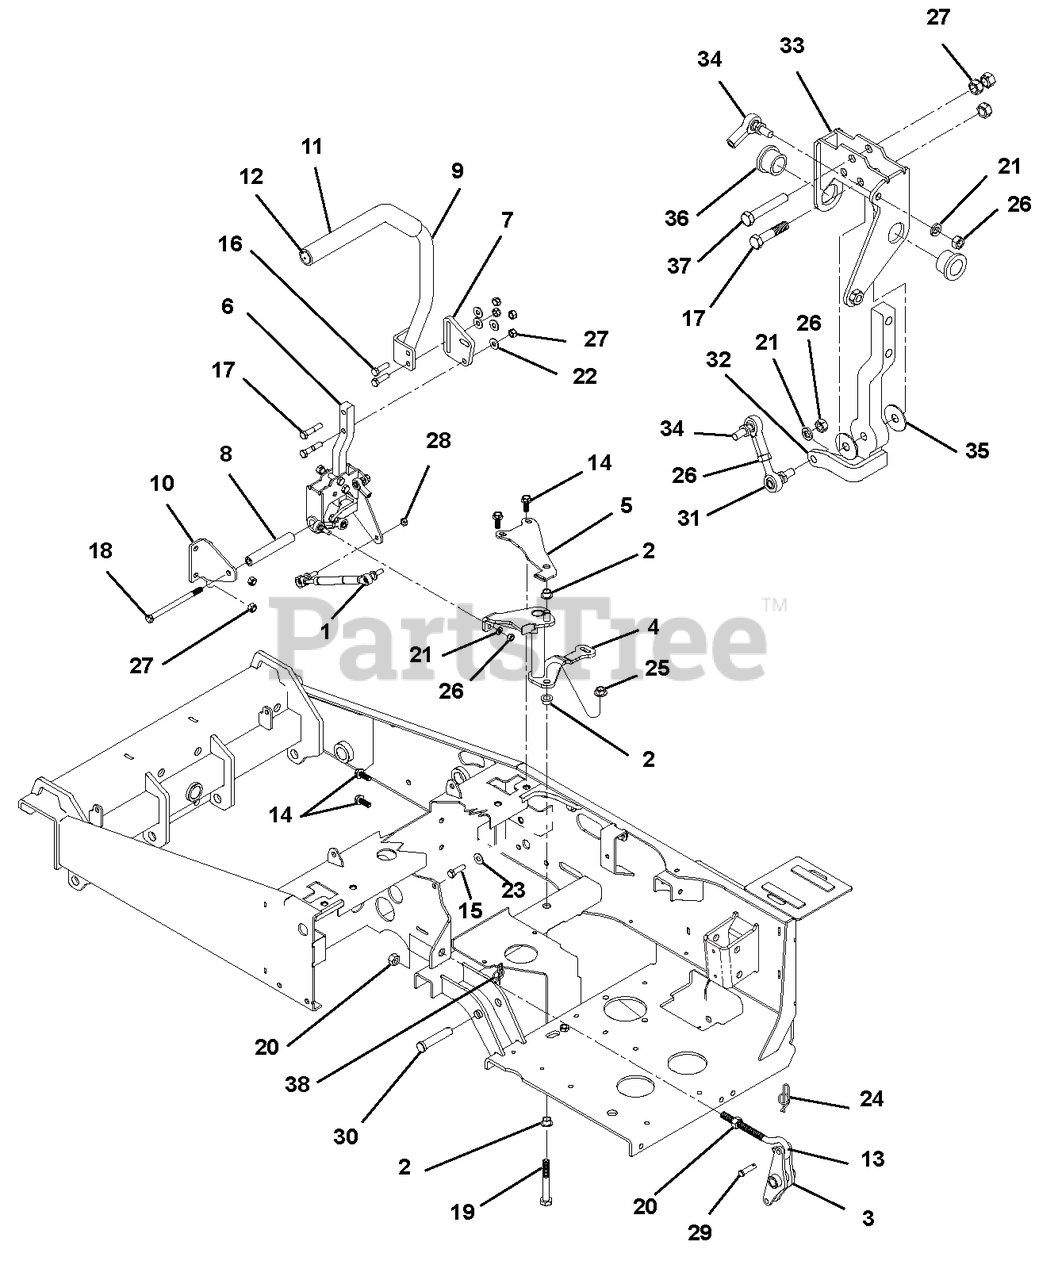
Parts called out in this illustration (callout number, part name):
1	DAMPNER, STEERING CONTROL
2	BRG, FLG .502X.629X.421
3	WLDT, SPRING PIVOT
4	WLDT, RH PARK BRAKE CONTROL
4	WLDT, LH PARK BRAKE CONTROL
5	EAR, RH BRAKE PIVOT
5	EAR, LH BRAKE PIVOT
6	WLDT, RH STEERING BAR
6	WLDT, LH STEERING BAR
7	PLATE, HANDLE HEIGHT
8	TUBE, RD .750 X .179 X 4.69 Y
9	WLDT, RH STEERING HANDLE
9	WLDT, LH STEERING HANDLE
10	PLATE, BENT
11	FOAM GRIP
11	GRIP, HANDLE
12	PLUG, 7/8" END
13	EYEBOLT, 1/2-13X1.00X4.50 FL Y
14	BOLT, 3/8-16X1.00 FGH 8 Y
15	@BLT-HEX .38-16X.75 GR5 YWZC
16	@BLT-HEX .38-16X1.25 GR5 YWZC
17	@BLT-HEX .38-16X1.75 GR5 YWZC
18	@BLT-HEX .38-16X5.50 GR5 YWZC
19	@BLT-HEX .50-13X2.75 GR5 YWZC
20	@NUT-HEX .50-13 YWZC
21	@WSHR-LK .31X.078 REG YWZC
22	@WSHR-FL-STL.38X.875X.083 YWZC
23	@WSHR-FL-STL.438X1.00X.083 YWZ
24	RING, RUE .375 X .054 X 1.254
25	NUT-LK-CONE .50-13 GR C YWZC
26	NUT-HEX .312-24 YWZC
27	NUT-LK-FLG .375-16 PL
28	NUT-LK-TOP M8-1.25 YWZC
29	PIN-CLEV .375X1.38X1.14 YWZC
30	PIN-CLEV .625X3.00X2.77 YWZC
31	BALL JOINT, RH 5/16 MALE W/STD
32	WLDT, RH STEERING BAR
32	WLDT, LH STEERING BAR
33	WLDT, HANDLE CONTROL RH
33	WLDT, HANDLE CONTROL LH
34	BALL JOINT, RH 5/16 FMAL W/STD
35	WASHER, .400X1.27X.062 NYLON
36	BUSHING, .750 X 1.00 X .750
37	@BLT-HEX .38-16X2.25 GR5 YWZC
38	RING, RUE .625 X .072 X 1.690
